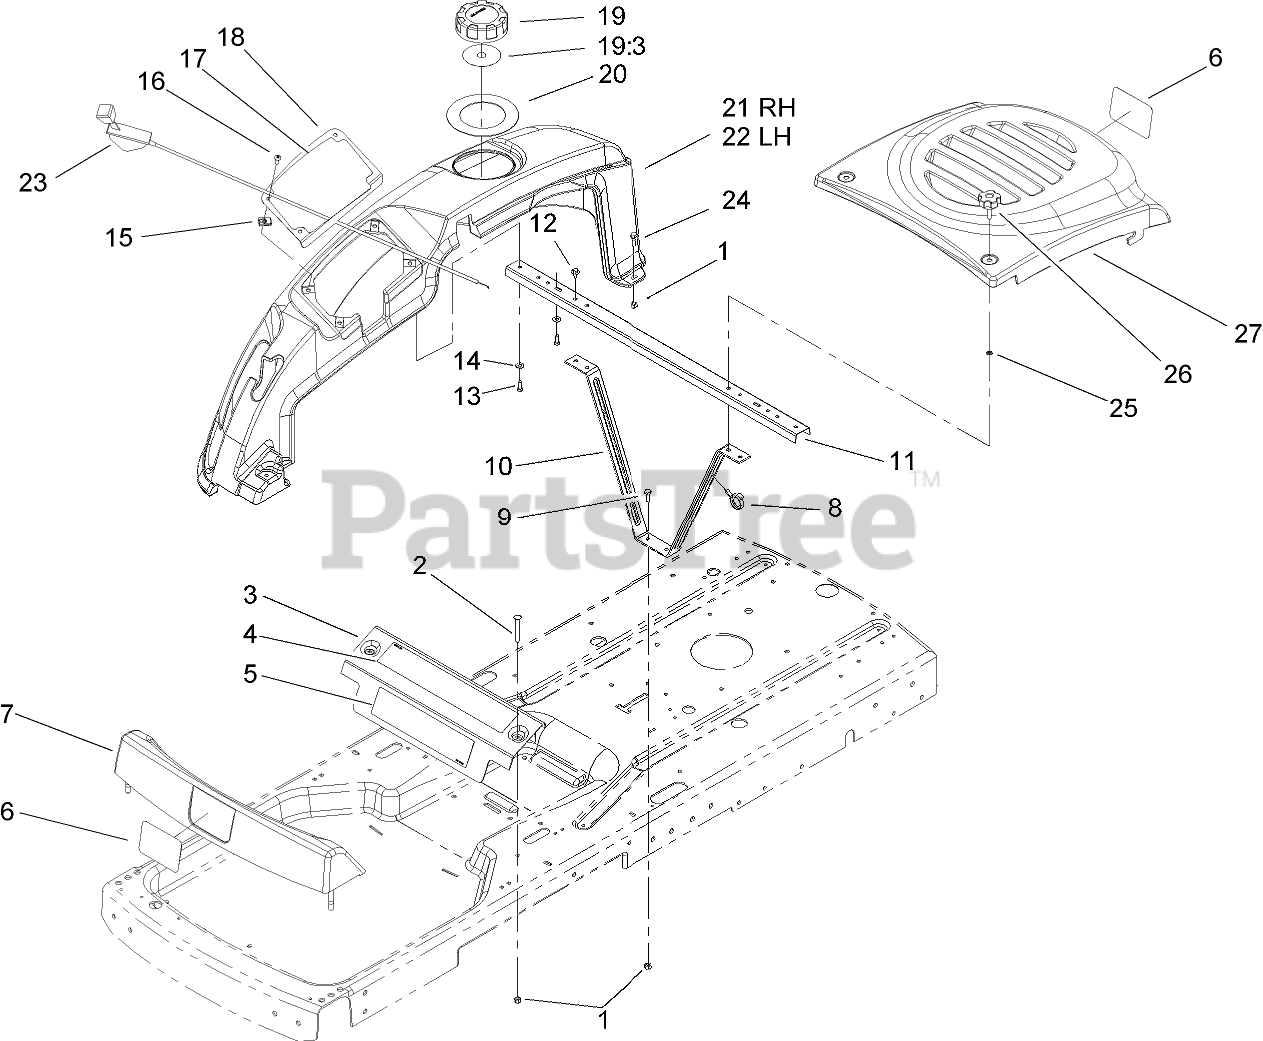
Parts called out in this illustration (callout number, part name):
1	NUT-LOCK, NI
2	SCREW-CARR
3	BRACKET-SUPPORT, FRONT
4	DECAL-DANGER
7	FOOTREST ASM
8	CLAMP-HOSE
9	SCREW-HH
10	BRACE ASM
11	CHANNEL-CROSS
12	SCREW-HHFTF
13	SCREW-PLASTITE
14	WASHER-FLAT
16	SCREW-PRH
17	DECAL-CONTROL
18	PANEL-CONTROL
19	GAS CAP ASM
19:3	GASKET-CAP, GAS
20	SEAL-RUBBER
21	COVER-SIDE, RH
23	CABLE-THROTTLE
24	SCREW-SHOULDER
25	NUT-RETAINER
27	COVER-HOOD
